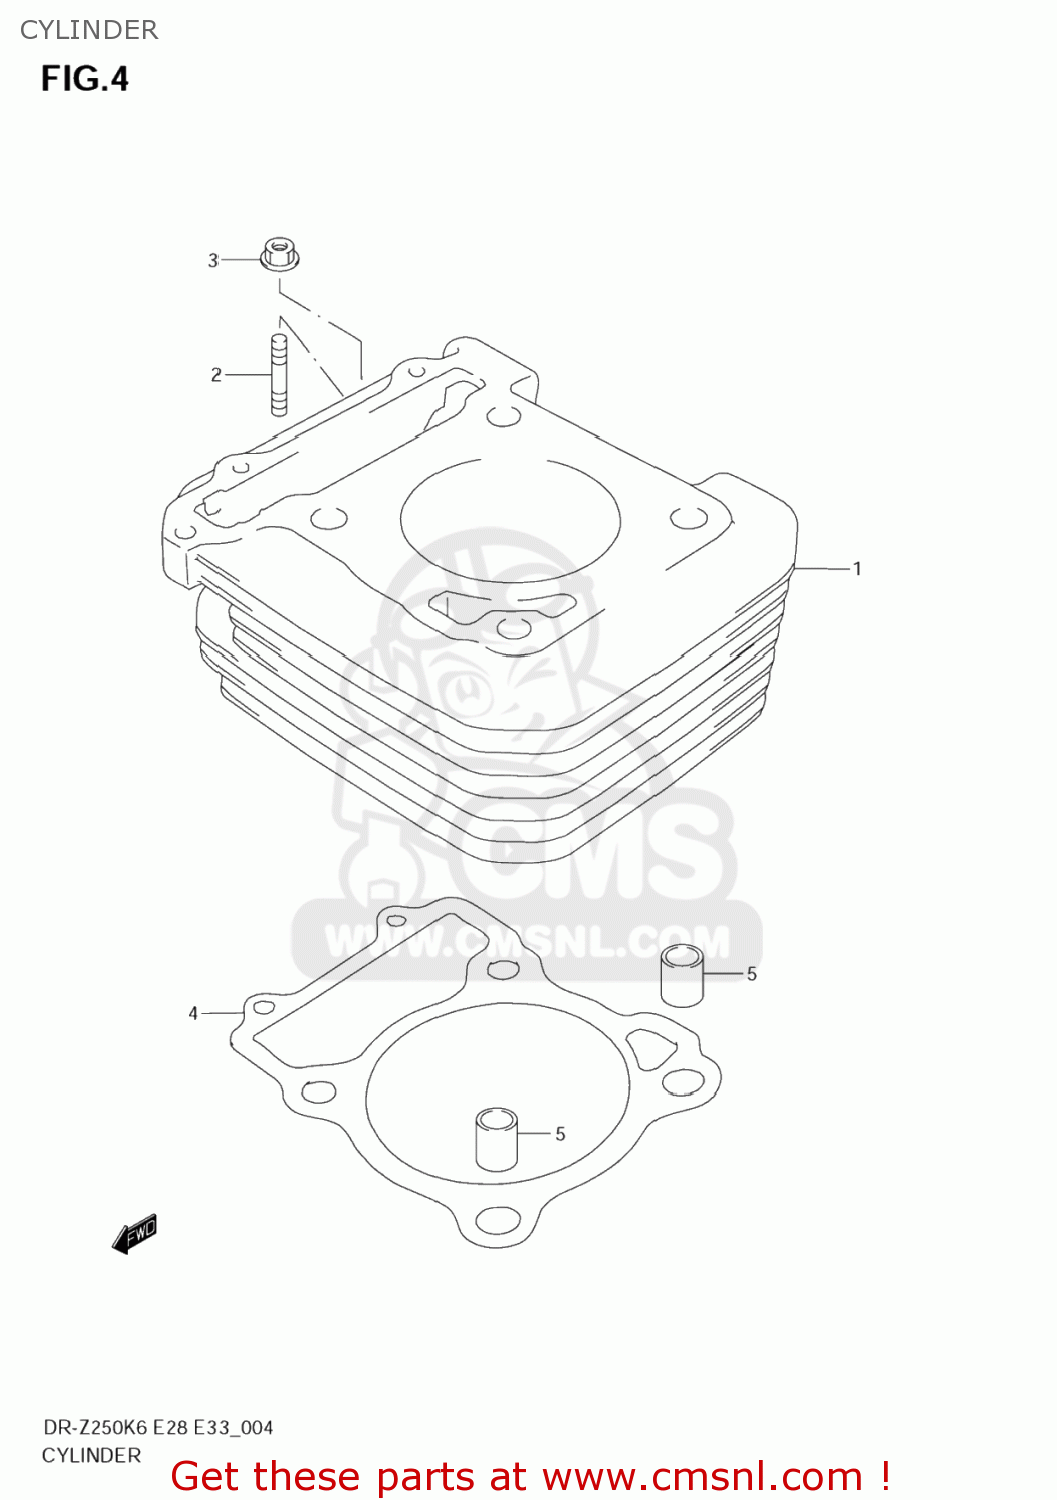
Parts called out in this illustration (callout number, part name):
1	CYLINDER
2	BOLT,STUD
3	NUT
4	GASKET,CYLINDER
5	PIN
